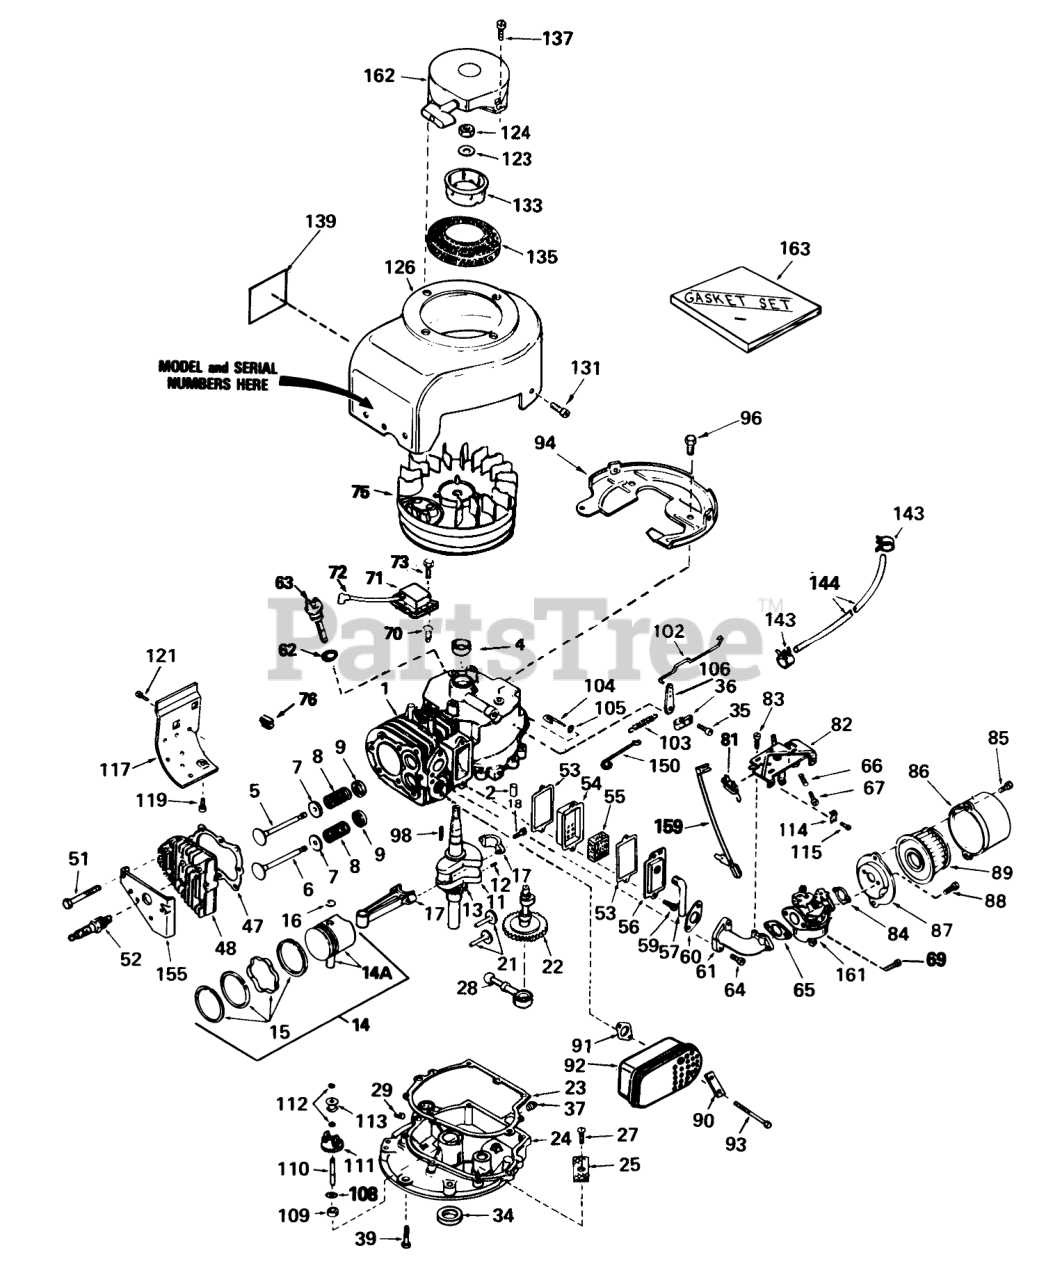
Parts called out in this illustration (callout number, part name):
1	Cylinder Assy. (Incl. Ref. #2 & 4)
2	Pin-Dowel
4	Oil Seal
5	Valve, Intake (Std.)(Incl. Ref. #9)
5	Valve, Intake (1/32" Oversize)(Incl. Ref. #9)
6	Valve, Exhaust (Std.)(Incl. Ref. #9)
6	Valve, Exhaust (1/32" Oversize)(Incl. Ref. #9)
7	Cap-Spring, Valve
8	Spring-Valve
9	Keeper-Spring, Valve
11	Crankshaft Assy. (Incl. Ref. #12 & 13)
12	Pin, Groove
13	Gear-Crankshaft
14	Piston, Pin & Ring Assy. (Std.)(Incl. Ref. #14A,15 & 16)
14	Piston, Pin & Ring Assy. (.010 Oversize)(Incl. Ref. #14A,15 & 16)
14	Piston, Pin & Ring Assy. (.020 Oversize)(Incl. Ref. #14A,15 & 16)
14A	Piston & Pin Assy. (Std.)(Incl. Ref. #16)
14A	Piston & Pin Assy. (.010 Oversize)(Incl. Ref. #16)
14A	Piston & Pin Assy. (.020 Oversize)(Incl. Ref. #16)
15	Ring Set (Std.)
15	Ring Set (.020" OS)
15	Ring Set (.010" OS)
16	Ring-Retaining, Piston Pin
17	Rod Assy., Connecting (Incl. Ref. #18)
18	Bolt, Connecting Rod
21	Lifter-Valve
22	Camshaft (Mechanical Compression Release)
23	Gasket-Cover, Cylinder
24	Flange Assy., Mounting (Incl. #25,27,34,37,108&110)
25	Screen-Oil Filter
28	Pump, Oil
29	Plug-Pipe (Internal Hex, 1/4-18)
34	Seal-Oil
35	Screw
36	Clamp-Lever, Governor
37	Plug-Drain, Oil (SQH 1/4-18)
39	Screw (1/4-20 x 1-1/4)
47	Gasket-Head, Cylinder
48	Head, Cylinder (Incl. 3 of No.51)
51	Screw (5/16-18 X 2-1/2)
52	Plug, Spark (J17LM or equiv.)
52	Plug, Spark (Champion RCJ-8)
53	Gasket-Breather
54	Body-Breather
55	Element-Breather
56	Cover-Valve
57	Tube-Breather
60	Gasket-Intake
61	Pipe-Intake
62	Gasket
63	Dipstick, Oil (Incl. Ref. #62)
64	Screw (T-30, 5/16-18x1-3/32)
65	Gasket
66	Spring-Compression
67	Screw
69	Screw-Hex Hd.
70	Stud
71	Solid State
72	Cover-Spark Plug
73	Screw
75	FIywheel
76	Clip-Wire
81	Terminal
82	Control Assy ., Speed (Incl. Ref. #66, 67 & 81)
83	Screw (10-24 x 9/16)
84	Gasket
86	Body-Air Cleaner
87	Bracket
88	Screw (10-32 x 1/2)
89	Element
90	Plate-Locking
91	Gasket Exhaust
92	Muffler
93	Screw Hex Hd.
94	Baffle Blower Housing
96	Screw (1/4-20x19/32)
98	Key-Flywheel
102	Link Governor
103	Spring Governor
104	Rod, Governor (Incl . Ref . #105)
105	Washer-Flat
106	Lever-Governor
108	Washer-Flat
109	Spacer Assy., Governor (Incl. Ref. #108)
110	Shaft, Governor
111	Gear Assy., Governor (Incl. Ref. #108)
112	Ring-Retaining
113	Spool-Governor
114	Conduit
115	Screw (10-32 x 3/8)
117	Extension-Blower Hsng.
121	Screw
123	Washer-Belleville
126	Housing Blower
133	Cup-Starter
135	Screen-Starter
139	Decal-Instruction
143	Clamp-Line, Fuel
144	Line-Fuel
150	Link Governor Spring
155	Cover-Head, Cylinder
159	Wire-Ground
161	Carburetor (Incl. Ref. #65)
162	tarter-Rewind
163	Gasket Set (Incl. Items Marked)
